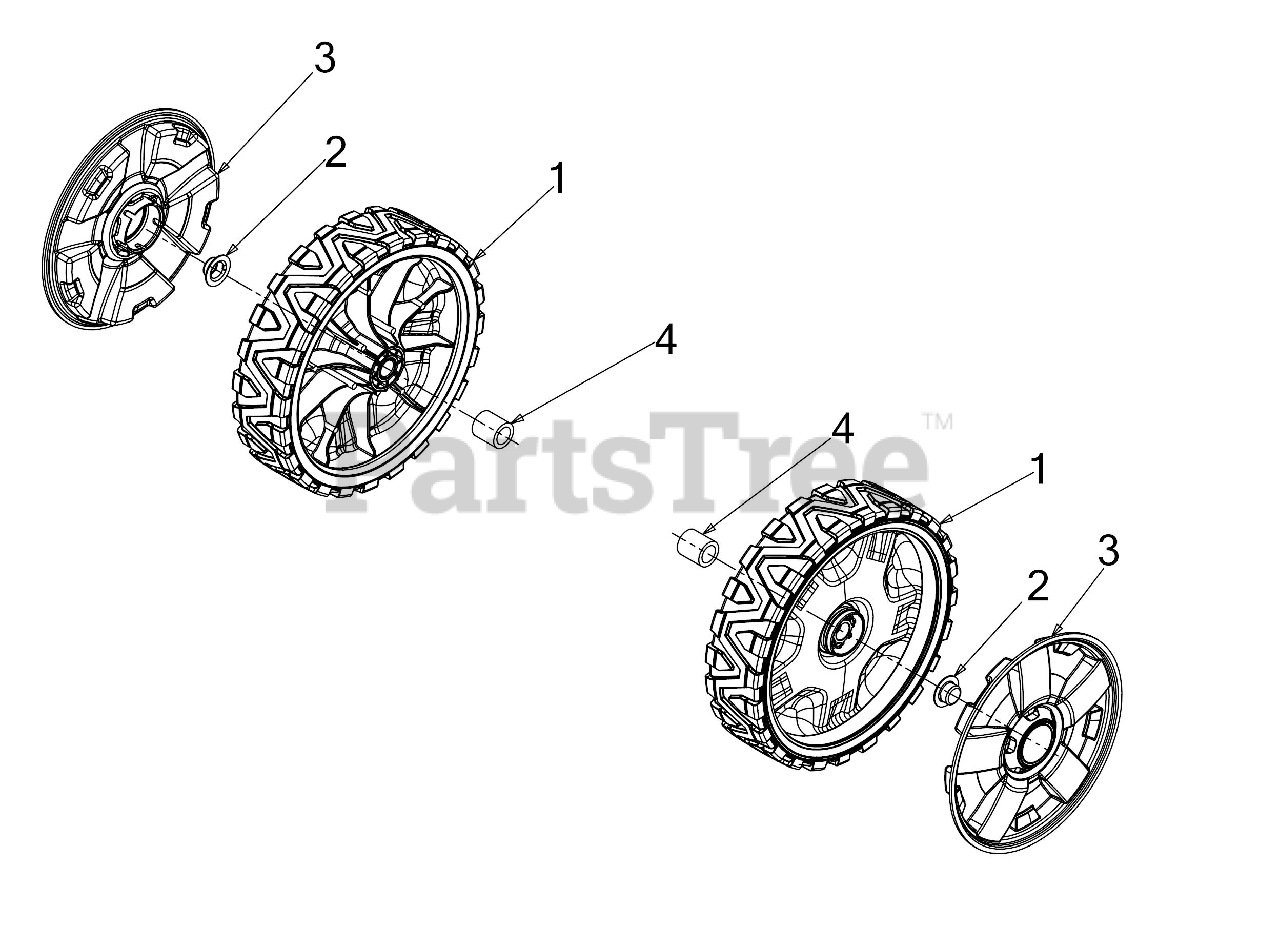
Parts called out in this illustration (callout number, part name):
1	WHEEL ASSEMBLY (8 x 2)
2	PUSH CAP
3	HUBCAP
4	SPACER .525 x .775
